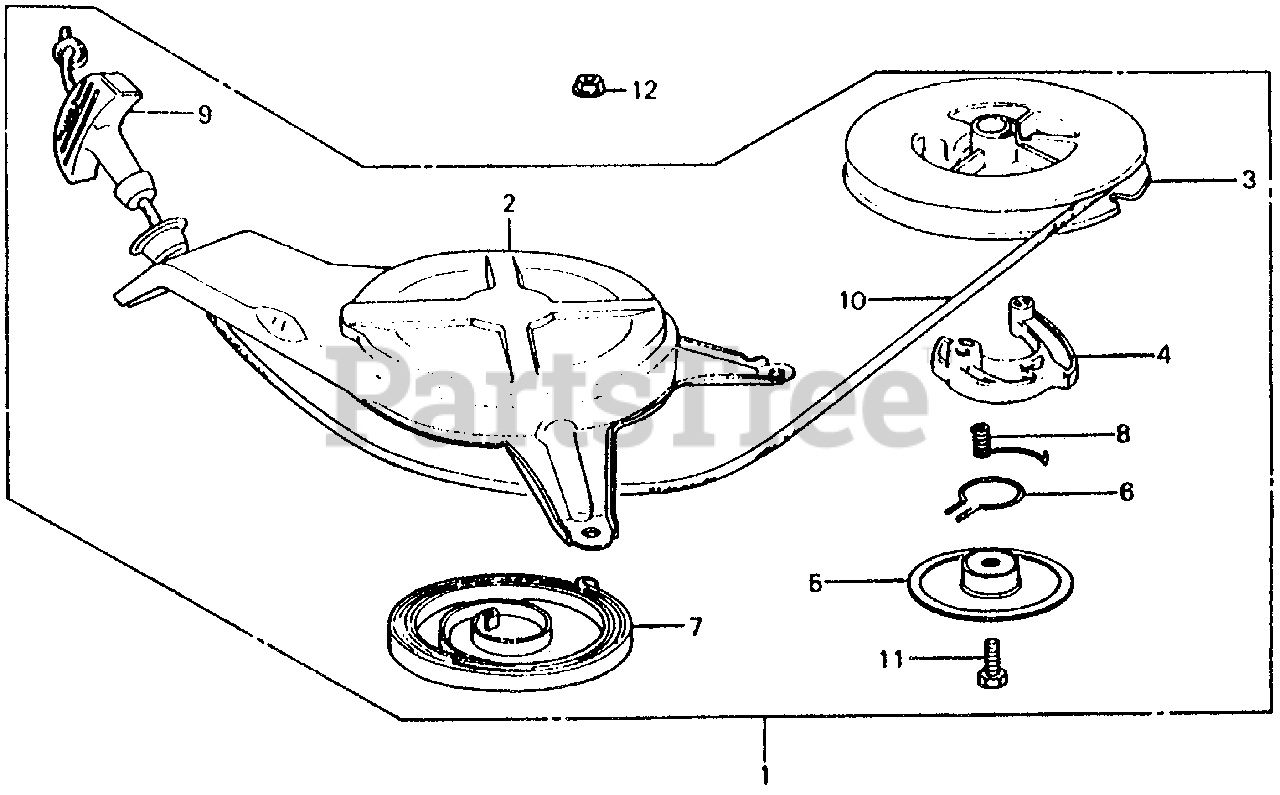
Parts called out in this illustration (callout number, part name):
1	STARTER ASSY., RECOIL (NOT AVAILABLE)
2	CASE, RECOIL STARTER (NOT AVAILABLE)
3	PULLEY, RECOIL STARTER
4	RATCHET, STARTER
5	PLATE, FRICTION
6	SPRING, FRICTION
7	SPRING, RETURN
8	SPRING, RETURN
9	KNOB, STARTER (NOT AVAILABLE)
10	ROPE, RECOIL STARTER (#4X55")
10	ROPE (#4X55")
11	BOLT, HEX. (6X20)
12	NUT, FLANGE (5MM)
